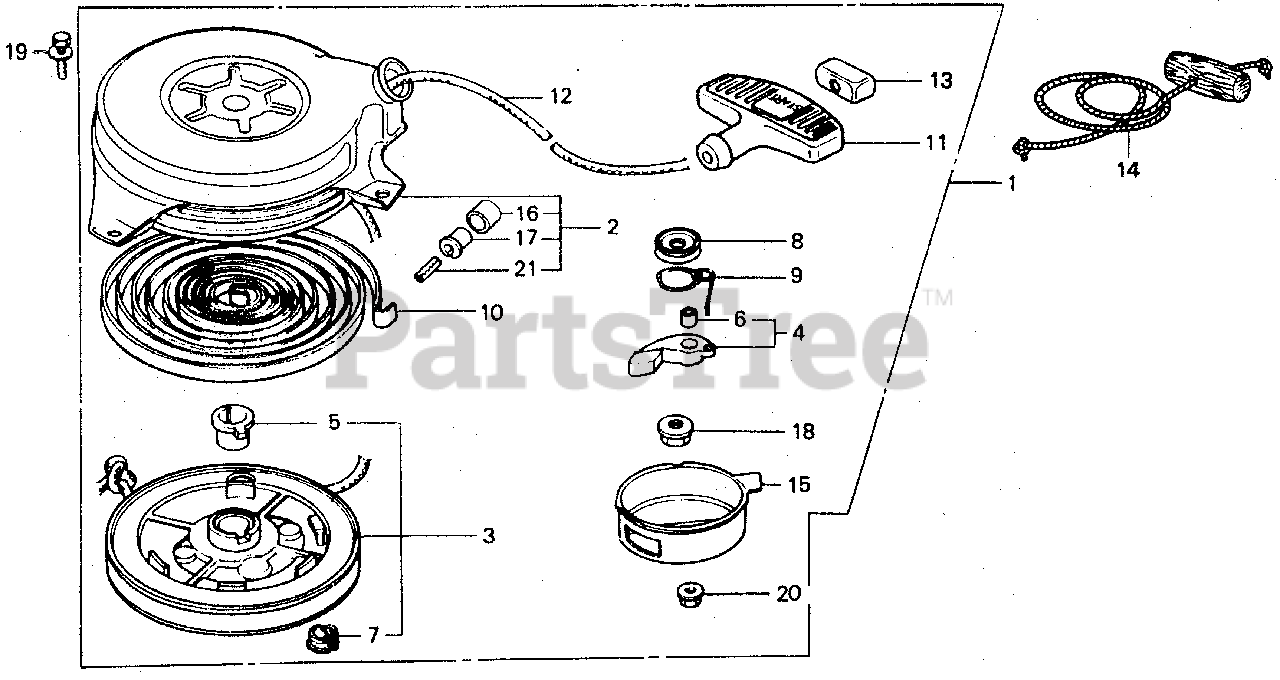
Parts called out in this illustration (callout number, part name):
1	STARTER ASSY., RECOIL *R8* (Honda Code 0957050). (BRIGHT RED)
2	CASE, STARTER *R8* (Honda Code 1024405). (BRIGHT RED)
3	REEL, STARTER
4	RATCHET
5	BOSS, REEL
6	BUSH, RATCHET
7	BUSH, REEL STARTER
8	PLATE, FRICTION
9	SPRING, FRICTION
10	SPRING, RETURN
11	GRIP, STARTER
12	ROPE, STARTER (#5X55")
13	SUPPORT, GRIP
14	ROPE, STARTER (#5X55") Use from Engine SN 1453515.
15	COVER, STARTER REEL Use up to Engine SN 1533900.
16	ROLLER, GUIDE
17	BUSH, ROLLER
18	NUT, SELF-LOCK (8MM)
19	BOLT-WASHER (6X10)
20	NUT, FLANGE (5MM)
21	PIN, SPRING (3X18)
